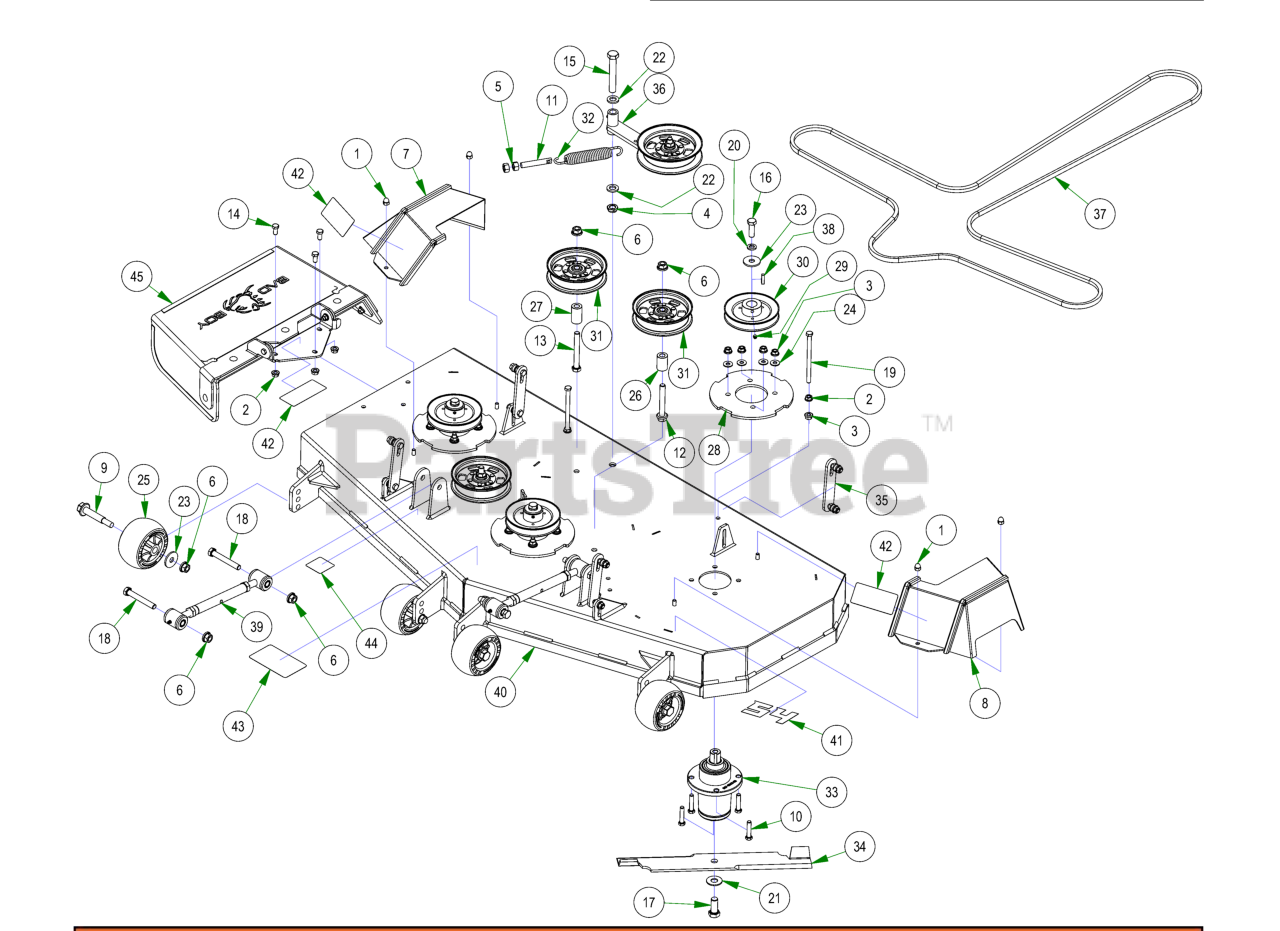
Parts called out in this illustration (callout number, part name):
1	5/16-18 ACORN NUT HIGH-CROWN ZC
2	3/8-16 HEX SERRATED FLANGE NUT HARD/ZINC
3	3/8-16 NYLON INSERT FLANGE LOCKNUT (GR.F) ZINC
4	5/8-11 NYLON INSERT JAM LOCKNUT ZINC
5	1/2-13 HEX NUT ZINC
6	1/2-13 NYLON INSERT FLANGE LOCKNUT ZINC
7	2021 Maverick 54”/60” RH Pulley Cover
8	2021 Maverick 54”/60” LH Pulley Cover
9	Deck Wheel Bolt
10	3/8-16 X 1-3/4 HEX C/S (GR.5) ZC
11	All Thread
12	1/2-13 X 3-1/2 HEX FLANGE BOLT (GR.8) ZINC
13	1/2-13 X 4 HEX CAP SCREW (GR.8) ZINC YELLOW
14	3/8-16 X 3/4 HEX CAP SCREW (GR.5) ZINC
15	5/8-11 X 4 HEX CAP SCREW (GR.8) ZINC YELLOW
16	1/2-20 X 1-1/2 HEX CAP SCREW (GR.5) ZINC
17	5/8-18 X 1-1/2 HEX CAP SCREW (GR.8) ZINC YELLOW
18	1/2-13 X 3-1/2 HEX CAP SCREW (GR.5) ZINC
19	3/8-16 X 5-1/2 HEX CAP SCREW (GR.5) ZINC
20	1/2 SPLIT LOCKWASHER (GR.8) ZINC/YELLOW
21	5/8 USS FLAT WASHER (1-3/4" OD) GR.8 ZINC YELLOW
22	.635 ID X 1.120 OD X .140 THICK FLAT WASHER NYLON
23	1/2 BELLEVILLE WASHER (1-5/8 OD X .140 THK) ZINC
24	5/16 USS FLAT WASHER (7/8 OD) ZINC
25	Deck Wheel
26	.502 ID X .750 OD X 1.500 Long Spacer
27	1 3/4" Pulley Spacer
28	Deck Spindle Support Plate
29	5/16-24 X 1/4 SOCKET SET SCREW (CUP PT) PLAIN
30	5.25" Deck Spindle Pulley
31	5-3/4 Idler Pulley
32	Deck Idler Spring
33	Spindle Assembly
34	54" Fusion Blade for Avenger/ZT/Mav/Outlaw/Revolt
35	Deck Hanger Assembly
36	2017 MZ/ZT Deck Idler Assembly
37	B155.75 Deck Belt
38	1/4 X 1 SQ MACHINERY KEY 1018 STL PLN
39	2018 Maverick Turnbuckle (Top Link)
40	2023 54" x 5" Deck
41	54" Deck Decal
42	Danger Decal-Spindle/Discharge
43	Deck Belt Route Decal
44	Deck Impact Patent Decal 9591803
45	Discharge Chute Assembly
